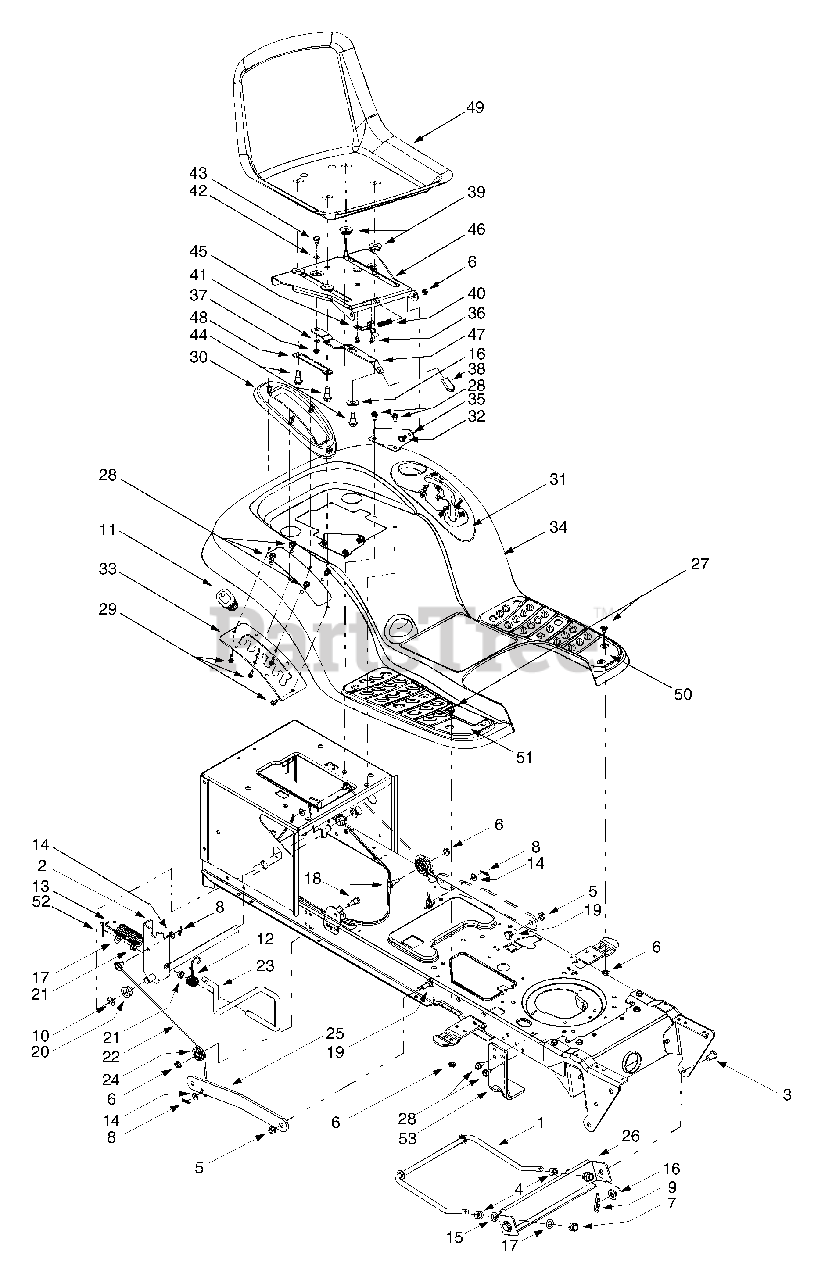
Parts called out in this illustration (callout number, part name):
3	Clevis Pin, .5 x .78
4	Hex Nut, 1/2-13
5	Flange Lock Nut, 3/8-16
6	Flange Lock Nut, 5/16-18
7	Hex Nut, 1/2-13
8	Internal Cotter Pin
9	Internal Cotter Pin
10	E-ring
11	Handle Grip
12	Torsion Spring
13	Lift-assist Spring, 1.15 x 5.99
14	Flat Washer, 5/16
15	Lock Washer, 1/2
16	Flat Washer, .31 x 1.062 x .134
17	Flat Washer, .51 x 1.12 x .06
18	Hex Cap Screw, 5/16-18 x .62
19	Shoulder Screw, 3/8-16
20	Hex Flange Bearing
21	Snap Flange Bearing
22	Lift Cable, 16.16
23	Lift Handle
24	Roller Pulley
27	Carriage Bolt, 5/16 x .62
28	Self-tapping Screw, 5/16-18 x .625
29	Self-tapping Screw, 1/4-15 x .75
30	Lift Lever Cover
31	Shift Lever Cover w/ Cup Holder
32	Shoulder Screw, .437 x 1.62
36	Screw, #10-16 x .375
37	Hex Flange Lock Nut, 1/4-20
38	Seat Adjuster Grip
39	Spacer
40	Compression Spring, .41 x 1.5
41	Spring Washer, .265 x .562 x .025
42	Flat Washer, .344 x .62 x .03
43	Shoulder Screw, .340 x .285,1/4-20
44	Shoulder Screw, .50 x .50, 3/8-16
45	Seat Stop
48	Seat Adjustment Selector
49	Seat, Radiant Yellow, Medium Back
50	LH Foot Pad
51	RH Foot Pad
52	Cotter Pin
